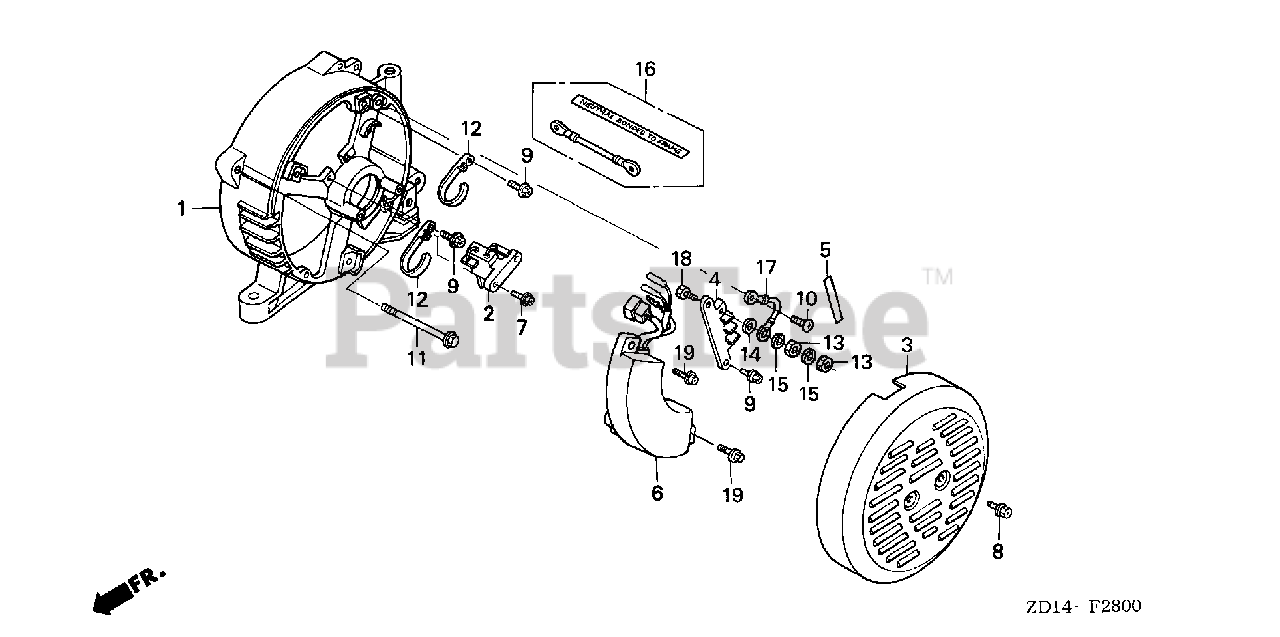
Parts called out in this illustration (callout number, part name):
1	HOUSING, RR.
2	BRUSH ASSY.
3	COVER, GENERATOR END *NH105* (MAT BLACK)
4	TERMINAL, VOLT CHANGE
5	MARK, VOLT
6	REGULATOR ASSY., AUTOMATIC VOLTAGE
7	SCREW, TAPPING (5X18)
8	SCREW, TAPPING (5X12)
9	SCREW, TAPPING (5X14)
10	SCREW, PAN (5X12)
11	BOLT, FLANGE (6X175)
12	TIE, CABLE
13	NUT, HEX. (5MM)
14	WASHER, PLAIN (5MM)
15	WASHER, SPRING (5MM)
16	WIRE SET, NEUTRAL BOND
17	WIRE, GROUND
18	BOLT, HEX. (5X20)
19	SCREW, TAPPING (5X16)
